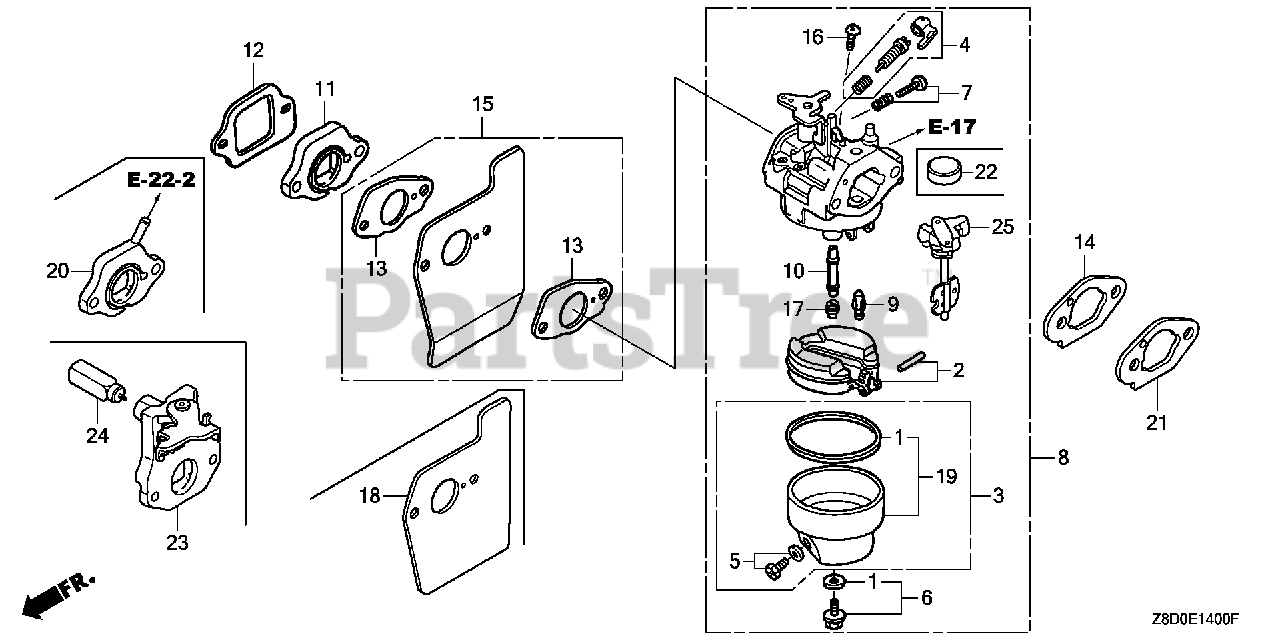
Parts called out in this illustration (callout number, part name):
1	GASKET SET
2	FLOAT SET
6	SCREW SET
8	CARBURETOR ASSY. (BB76B A)
8	CARBURETOR ASSY. (BB76E A)
9	VALVE, FLOAT (Honda Code 7934714). (CARBURETOR NO.)
10	NOZZLE, MAIN
11	INSULATOR, CARBURETOR
12	GASKET, INSULATOR
16	SCREW, PAN (5X6)
17	JET, MAIN (#55) Use up to Engine SN BB28A D.
17	JET, MAIN (#58) Use up to Engine SN BB28A D.
17	JET, MAIN (#60) (Honda Code 0635474). (CARBURETOR NO.)
17	JET, MAIN (#62) (Honda Code 0635482). (CARBURETOR NO.)
18	GUIDE, AIR
19	CHAMBER SET, FLOAT (CARBURETOR NO.)
25	CHOKE SET
